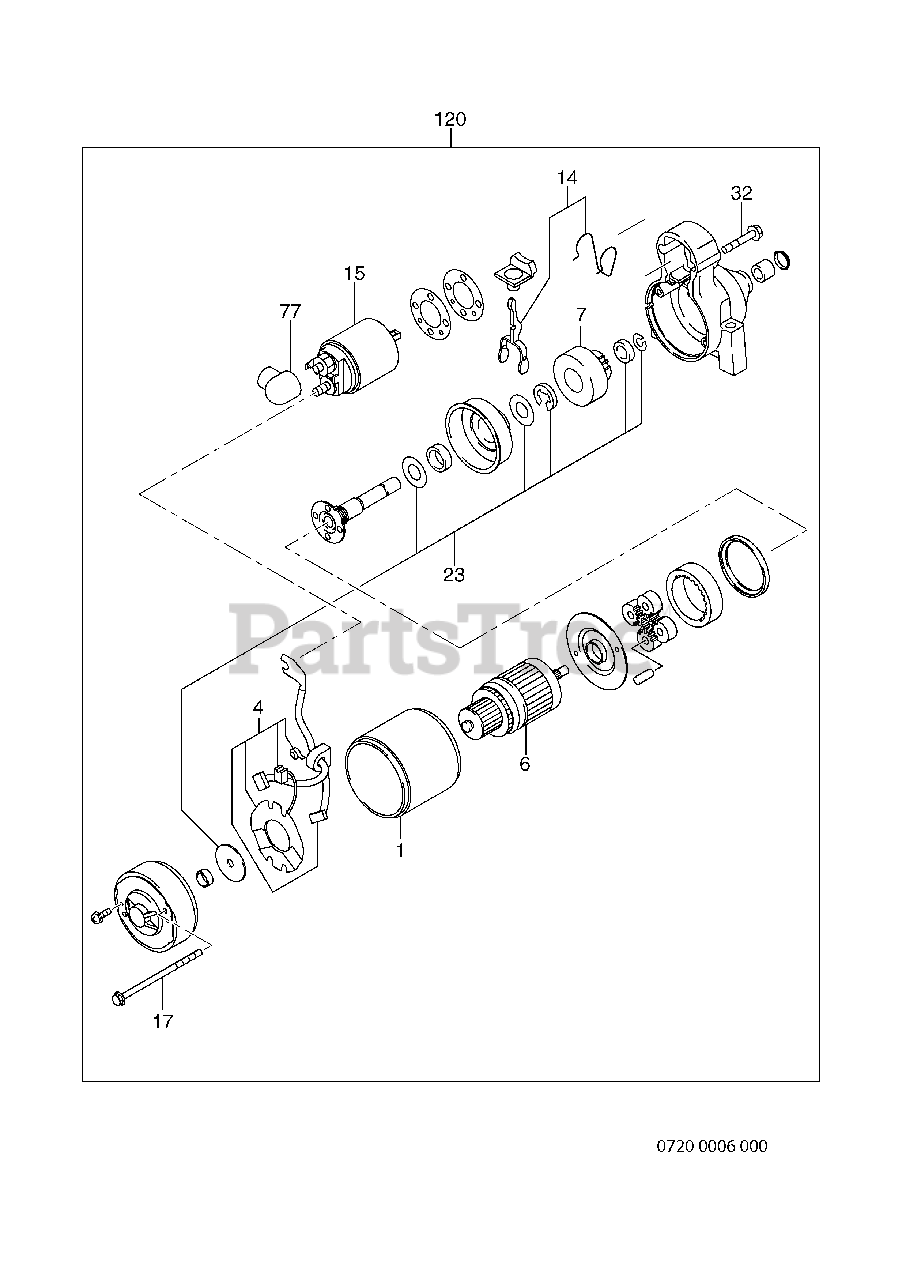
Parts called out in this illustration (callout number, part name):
1	MACHINE SHELL ASSEMBLY
4	BRUSH ASSEMBLY
6	ARMATURE
7	ONE-WAY CLUTCH
14	SHIFT LEVER SET
15	SOLENOID SWITCH
17	HEXAGON BOLTS WITH F
23	WASHER STOPPER SET
32	SHEATHING
120	STARTING MOTOR AY
